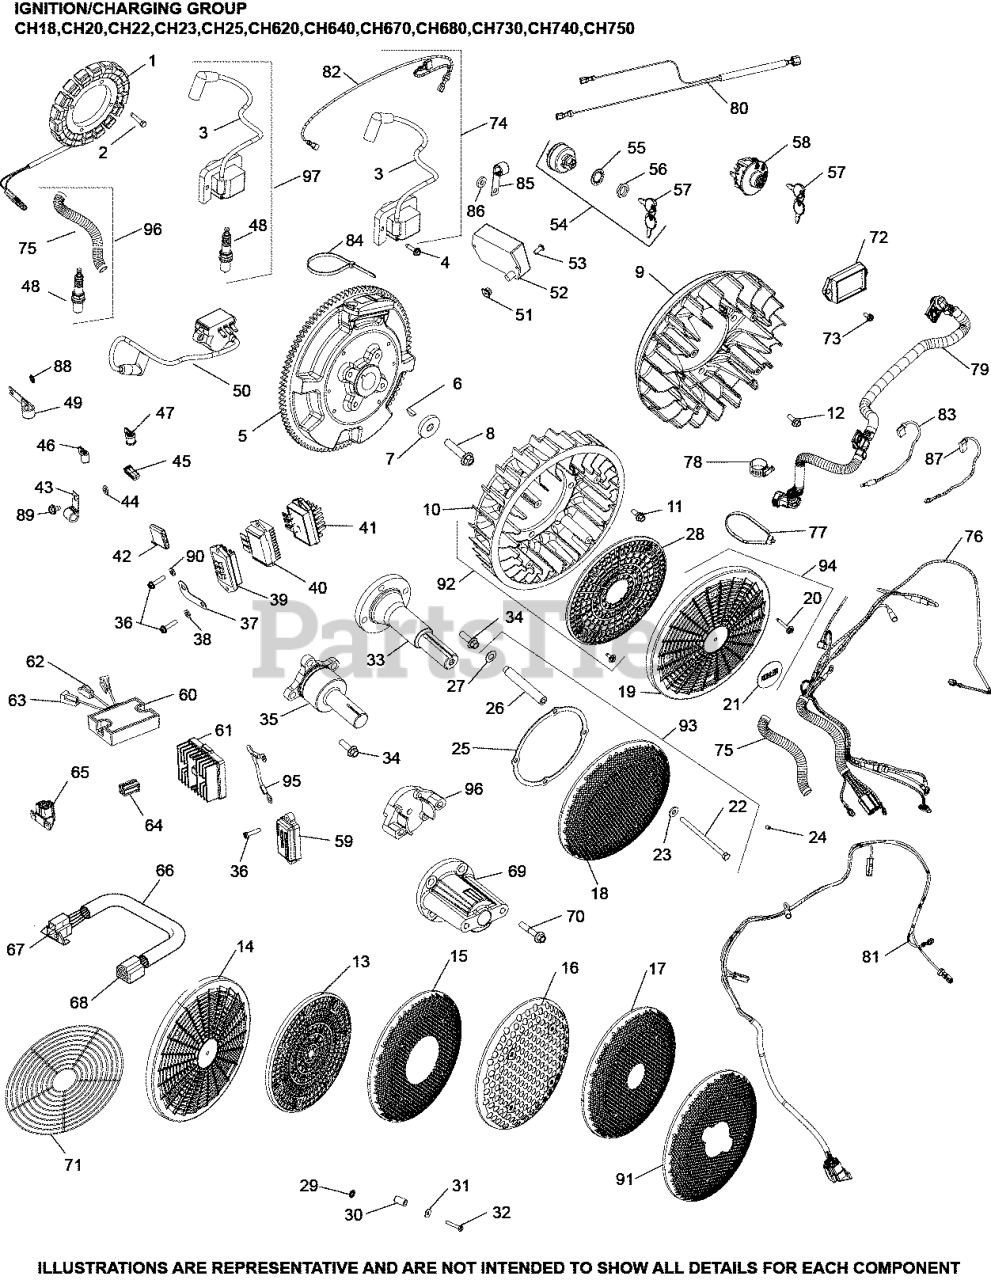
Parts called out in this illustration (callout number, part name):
1	KIT, 15 / 20 AMP STATOR
2	SCREW, THREAD FORMING
3	KIT, MODULE IGNTN (CDI FIXED)
4	SCREW, THREAD FORMING
6	KEY, 3/16" X 5/8"
7	WASHER, FLAT 13/32"
8	SCREW, FLG M10X1.5X45 - (#25086361S)
10	FAN USE 24 755 253-S
19	SCREEN, GRASS
22	SCREW, CAP M6X1.0X99.5
23	WASHER, FLAT 1/4" (O.D. 5/8")
24	SCREW, SKT SET #10-24X1/4"
25	RING, SUPPORT USE 25 141 08-S
27	WASHER, SPRING 10 MM
36	SCREW, HEX FLANGE HI-LO
39	REGULATOR/RECTIFIER USE 25 403 37-S
42	CONNECTOR
43	CLIP, CABLE
44	WASHER, FLAT 1/4" (O.D. 1/2")
48	PLUG, SPARK (PRO SERIES)
76	HARNESS, WIRING
90	WASHER, LOCK
